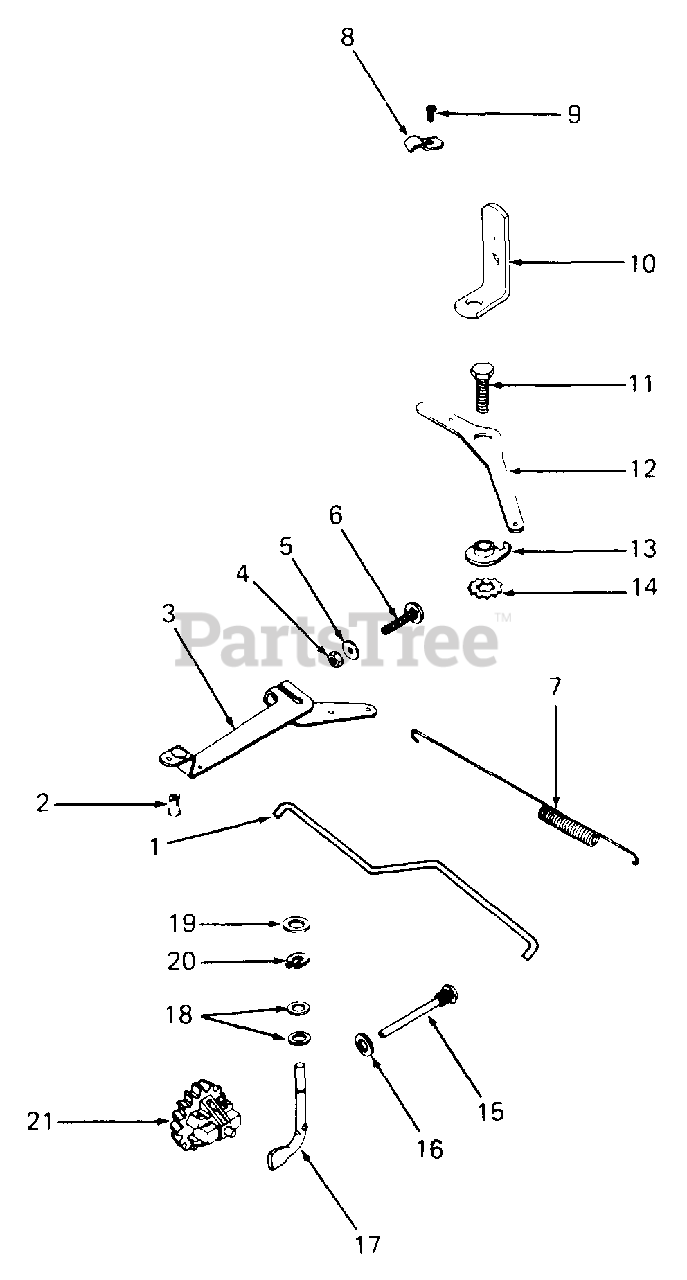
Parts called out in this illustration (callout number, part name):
1	Linkage, Governor
2	Bushing, Linkage Retaining
3	Arm, Governor
4	Nut, Hex, 1/4-20
5	Washer, Plain, 1/4
6	Screw, RH Sq Neck, 1/4-20 X 1.0 Lg
7	Spring, Governor
8	Clamp, Cable
9	Screw, Hex Cap, #10-24 X 7/16 Lg
10	Bracket, Throttle Cable
11	Screw, Hex Cap, 1/4-20 X .62 Lg
12	Lever, Speed Control
13	Stop, Governor
14	Washer, Lock
15	Pin, Governor Stop
16	Washer, Plain, 1/4
17	Shaft, Governor Stop
18	Washer, Plain, 1/4
19	Washer, Plain, 1/4
20	Retainer, Governor
21	Kit, Governor Gear
